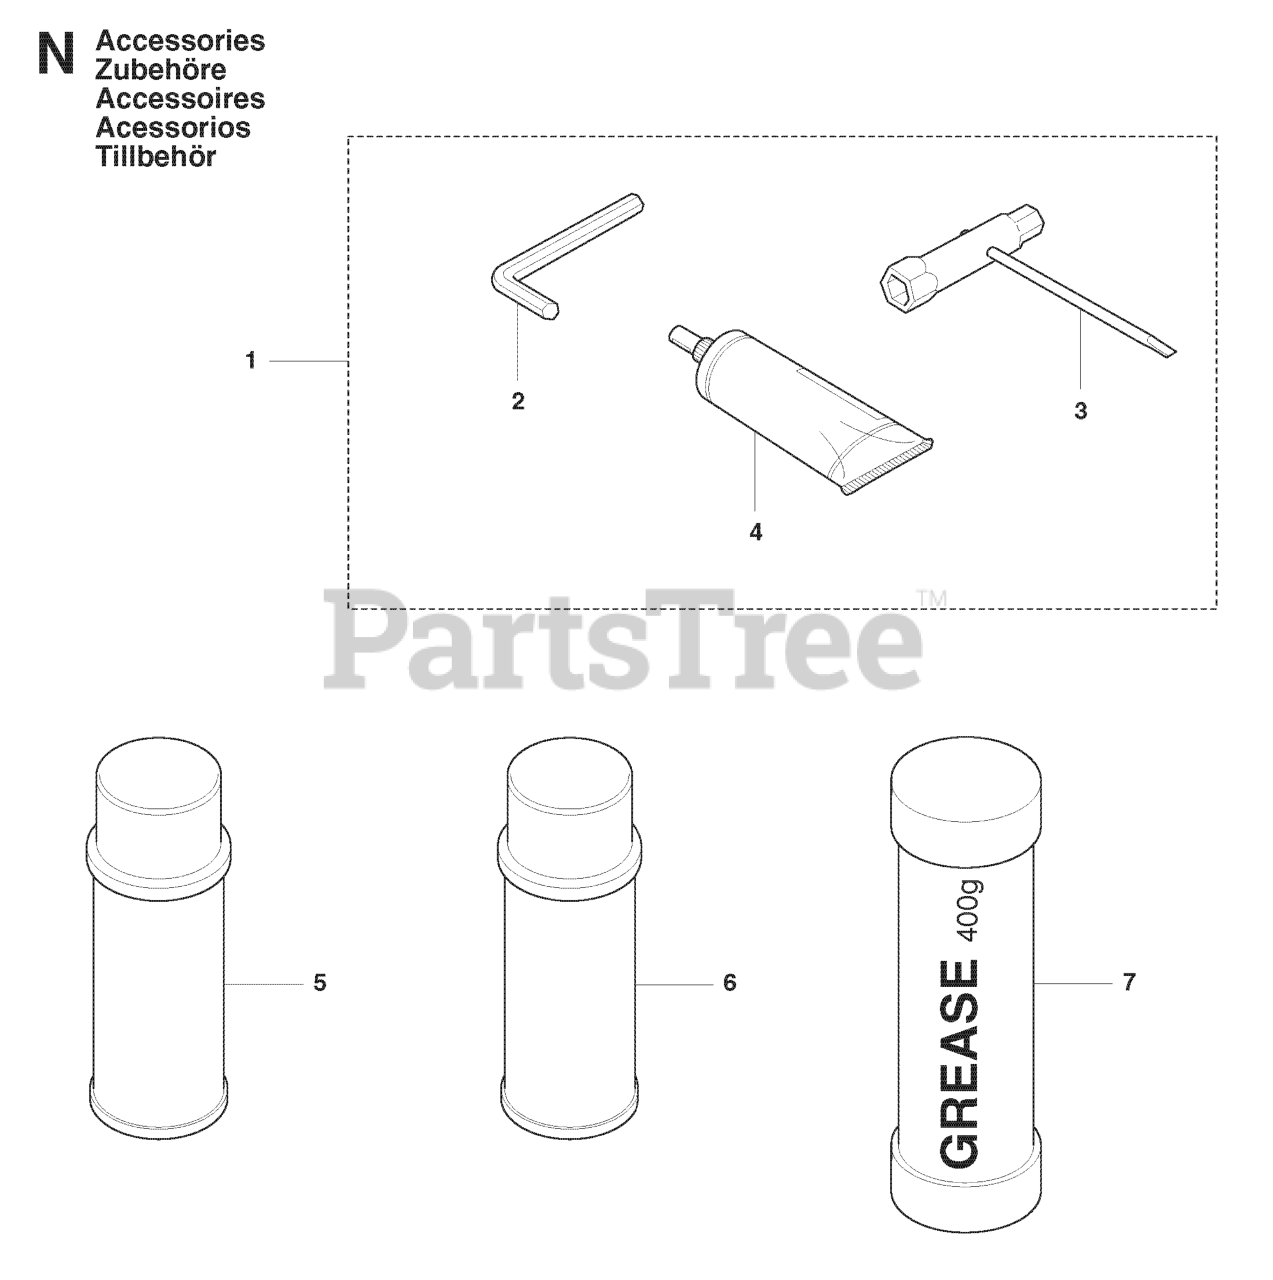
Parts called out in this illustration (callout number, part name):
3	COMBI TOOL
5	Ul 22 - 12 Pack
6	CUTTER BAR LUBE/12 PACK UL21
7	Grease 400 Grams
